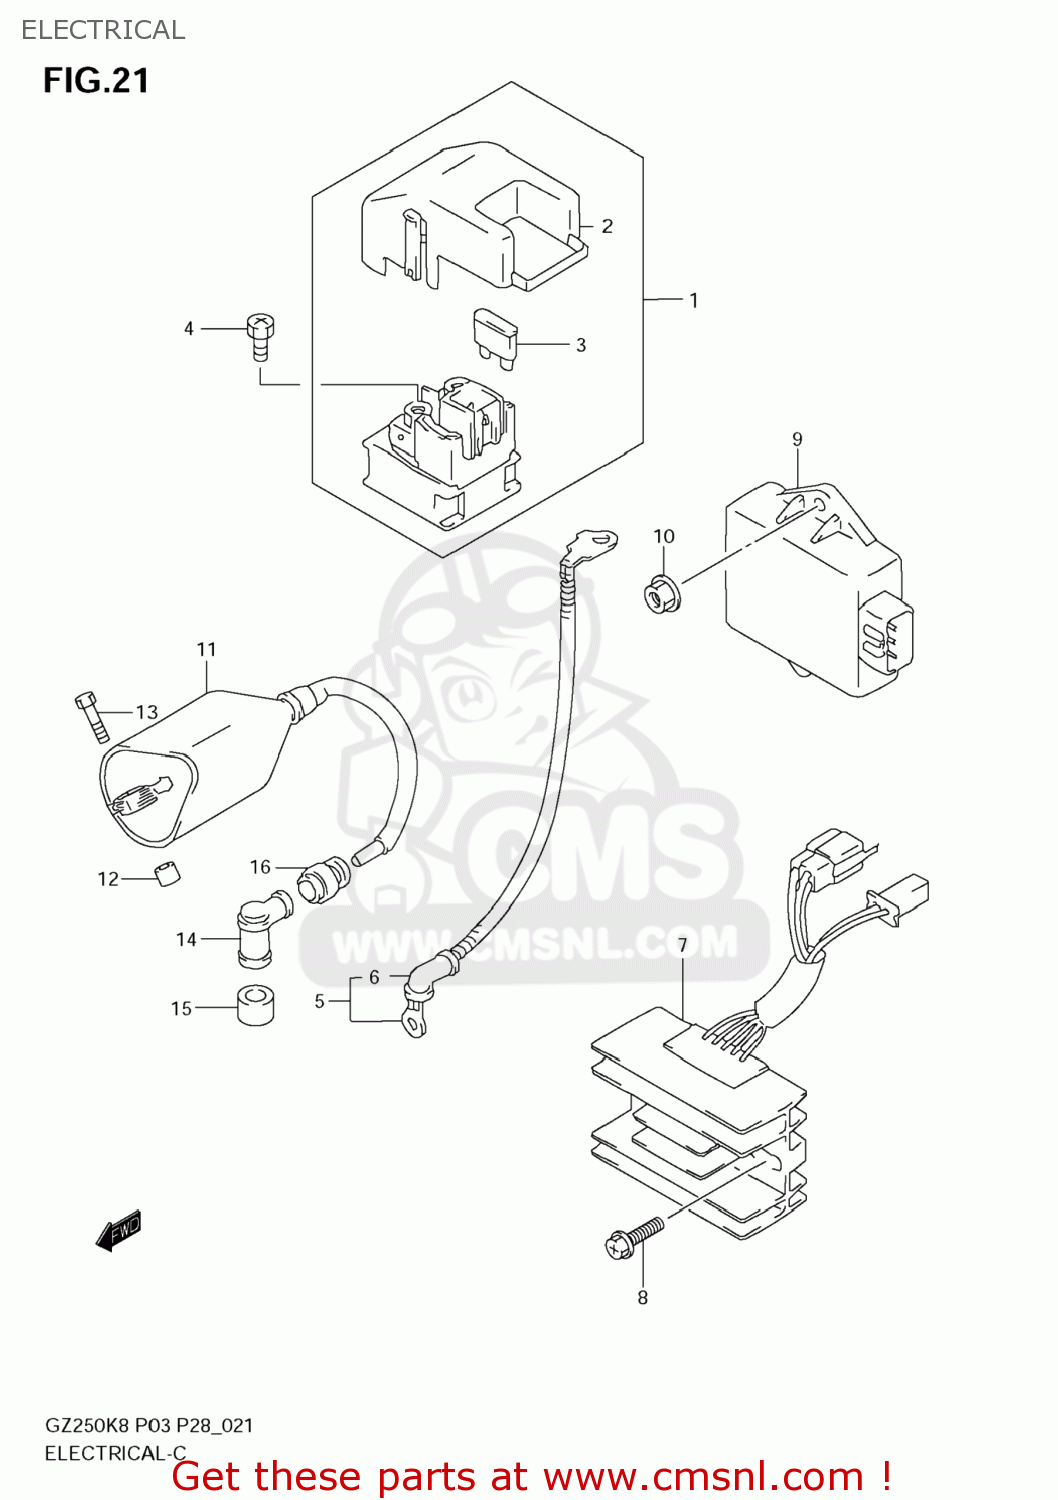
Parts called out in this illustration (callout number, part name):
1	RELAY ASSY, STARTING MOTOR
2	COVER
3	FUSE (20A)
4	SCREW(6X8)
5	WIRE STARTER M
6	CAP, STARTER MOTOR LEAD
7	RECTIFIER ASSY
8	SCREW
9	IGNITOR ASSY
10	NUT
11	COIL ASSY,IGNITION
12	SPACER(6.2X12X14)
13	BOLT
14	CAP ASSY,SPARK PLUG
15	SEAL,SPARK PLUG
16	SEAL,HIGH TENSION CORD
